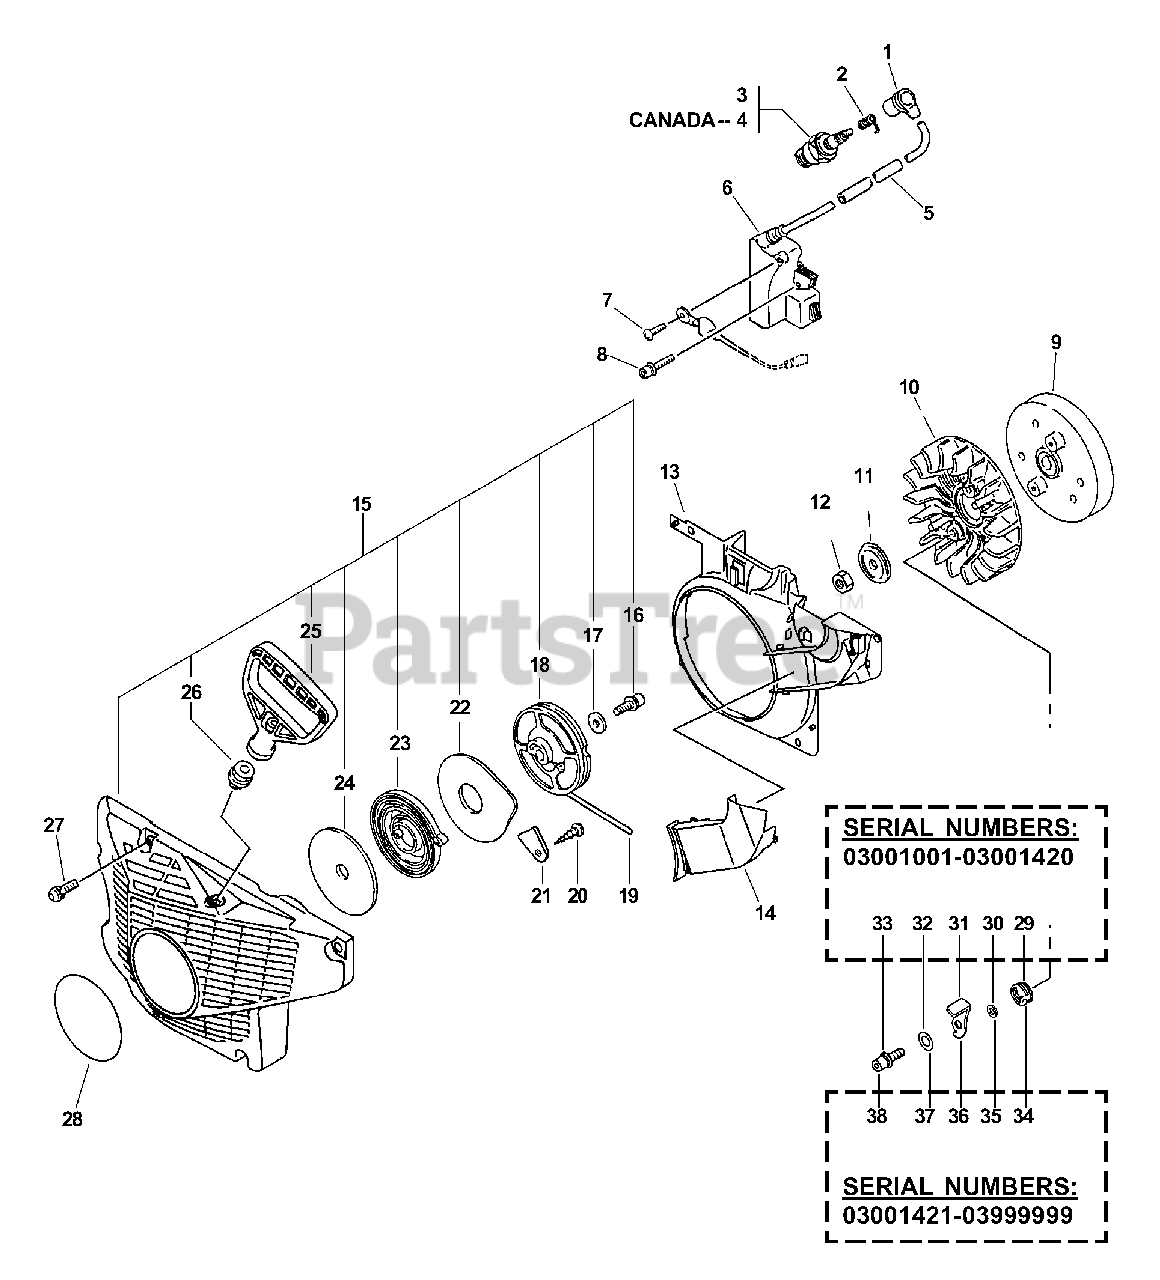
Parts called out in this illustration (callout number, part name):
1	CAP, SPARK PLUG
2	TERMINAL, SPARK PLUG CAP
3	SPARK PLUG -- BPM-7A
4	SPARK PLUG -- BPMR-7A
5	TUBE
6	COIL, IGNITION
7	SCREW - 4X8
8	SCREW - 4X20
9	FLYWHEEL
11	WASHER - CUP
13	COVER, FAN
14	DUCT, AIR
15	STARTER ASSY
16	SCREW - 5X14
17	WASHER - 5
18	REEL, ROPE
19	ROPE, STARTER - 4X950
20	SCREW - 4X8
21	RETAINER, BRAKE BAND
22	PLATE, STARTER
23	SPRING, REWIND
24	PLATE, STARTER
25	GRIP, STARTER
26	GUIDE, ROPE
27	SCREW - 5X20
28	LABEL - ECHO
29	SPRING, RETURN
31	PAWL, STARTER
32	WASHER - 5
33	SCREW - 5X14
34	SPRING, RETURN
35	SPACER, PAWL
36	PAWL, STARTER
37	WASHER - 5
38	SCREW - 5X20
